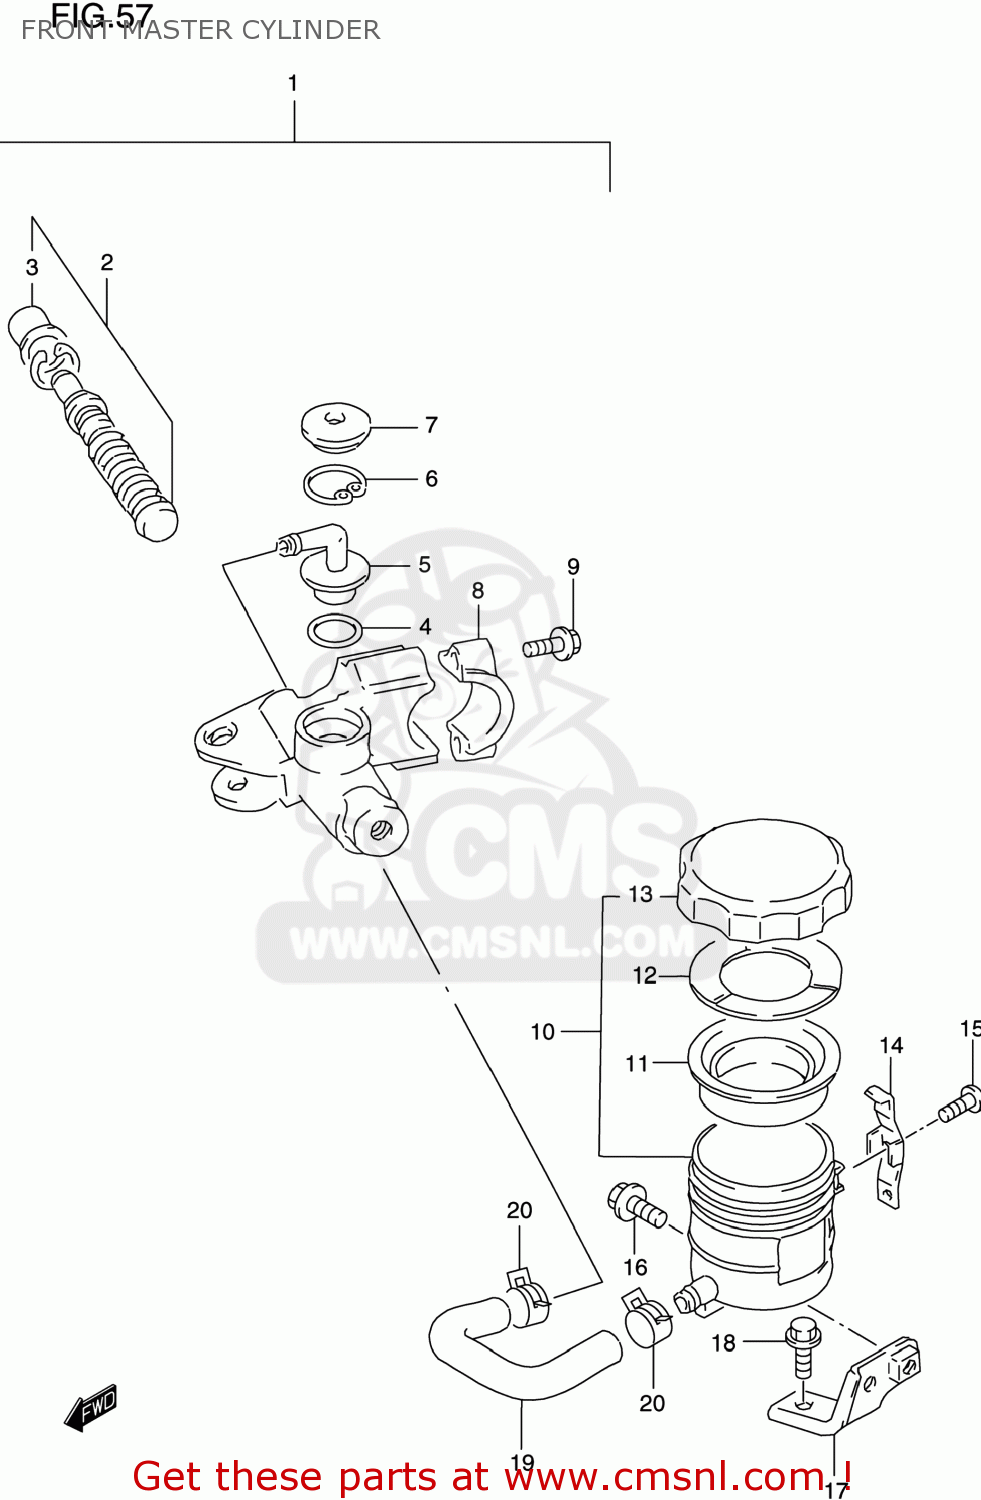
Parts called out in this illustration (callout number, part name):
1	CYLINDER ASSY,FR MASTER
2	PISTON & CUP SET
3	BOOT
4	O RING
5	CONNECTOR
6	CIRCLIP
7	COVER,DUST
8	HOLDER
9	BOLT(6X25)
10	TANK ASSY,RESERVOIR
11	DIAPHRAGM
12	PLATE,DIAPHRAGM
13	CAP
14	PLATE,RESERVOIR TANK CAP
15	SCREW
16	BOLT
17	BRACKET,RESERVOIR TANK
18	BOLT
19	HOSE,RESERVOIR TANK FR
20	CLAMP,RESERVOIR TANK FR
